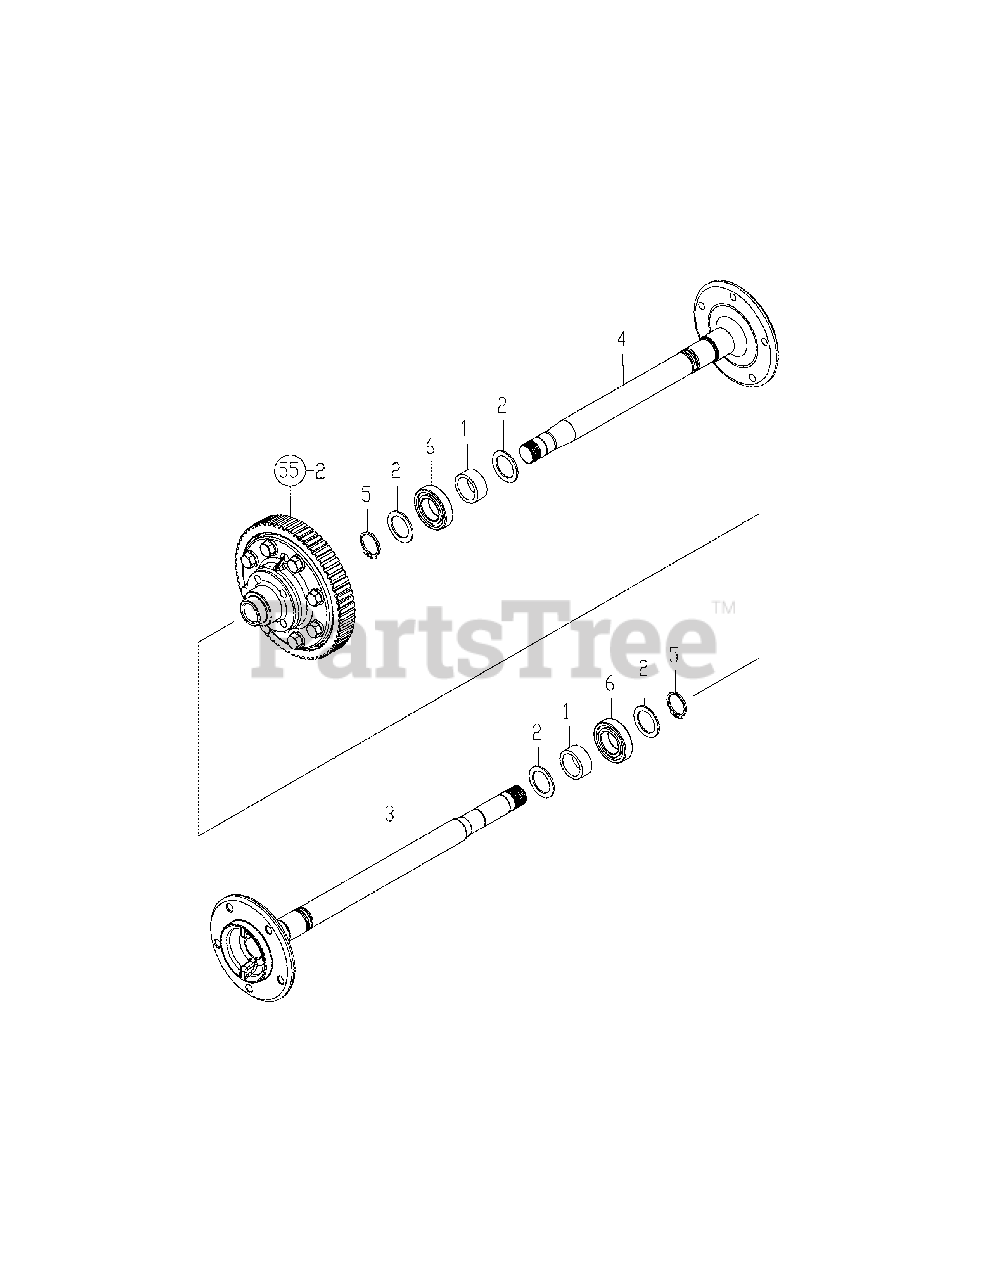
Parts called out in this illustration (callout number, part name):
1	Sleeve, 30X39X16
2	Collar, 30X42X2
3	Shaft, Rear Axle L
4	Shaft, Rear Axle R
6	Bearing, 6006 Ntn
